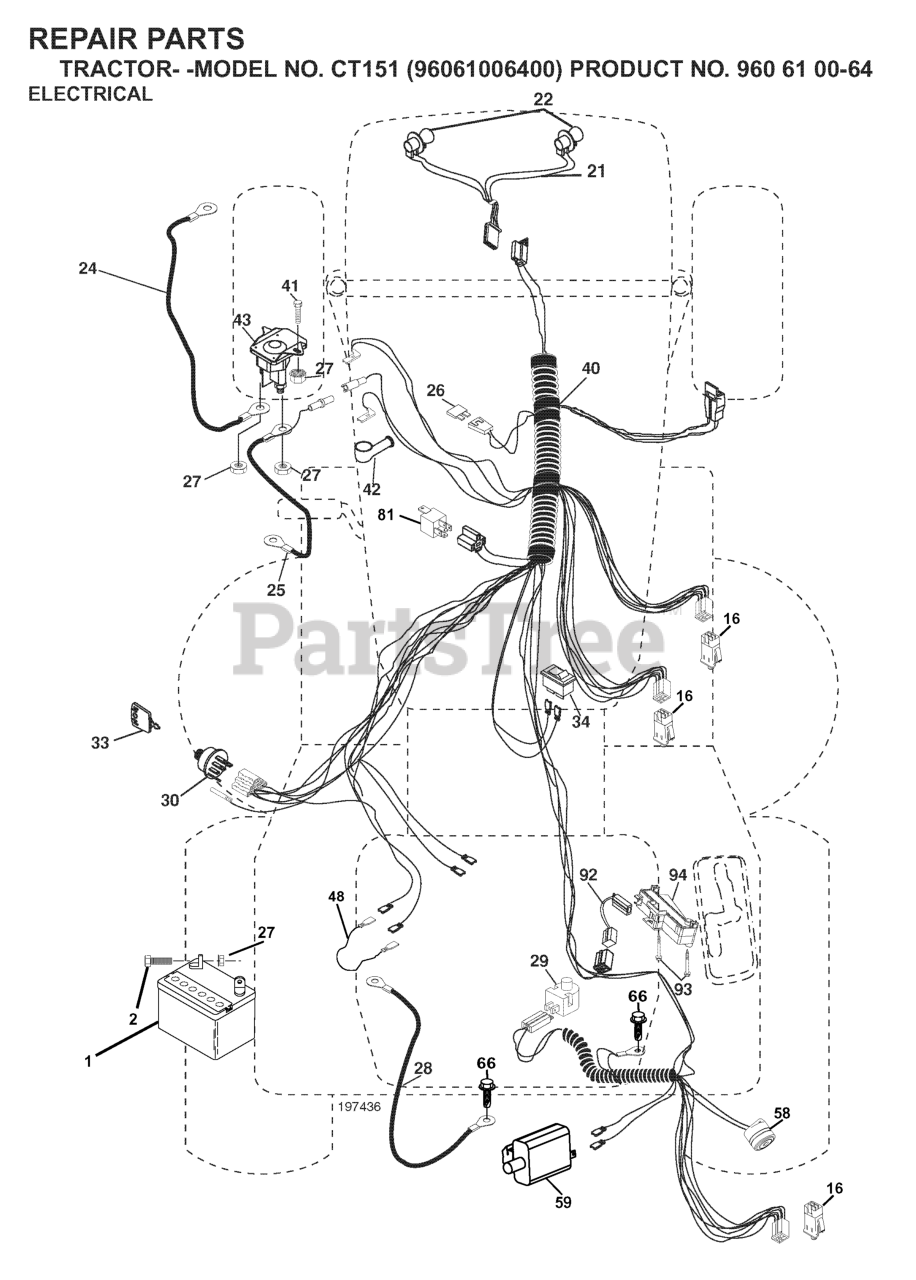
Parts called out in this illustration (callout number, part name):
1	BATTERY 12V .35 AMP
2	BOLT.HEX.1/4.X.3/4.DICHROMATE
16	SWITCH INTERLOOK PUSH-IN
21	HARNESS.W/LIGHT SOCKET
24	BATTERY CABLE GT
25	CABLE BATTERY
26	FUSE 20AMP
27	NUT
28	CABLE GROUND
29	SWITCH.SEAT.DP W/RAMPS
30	SWITCH.IGN.DELTA.W.LGH.ROS
33	KEY MLD GEN DELTA
41	BOLT
42	TERMINAL COVER
43	SOLENOID.W/BRASS.PLUNGER
48	ADAPTER.AMMETER
58	BUZZER
59	.WITCH.FULL BAGGER.INDICATOR
81	RELAY.ASSY.T
92	HARNESS.PIGTAIL.CONSLE
93	SCREW.PLASTITE
94	MODULE.REVERSE.ROS
